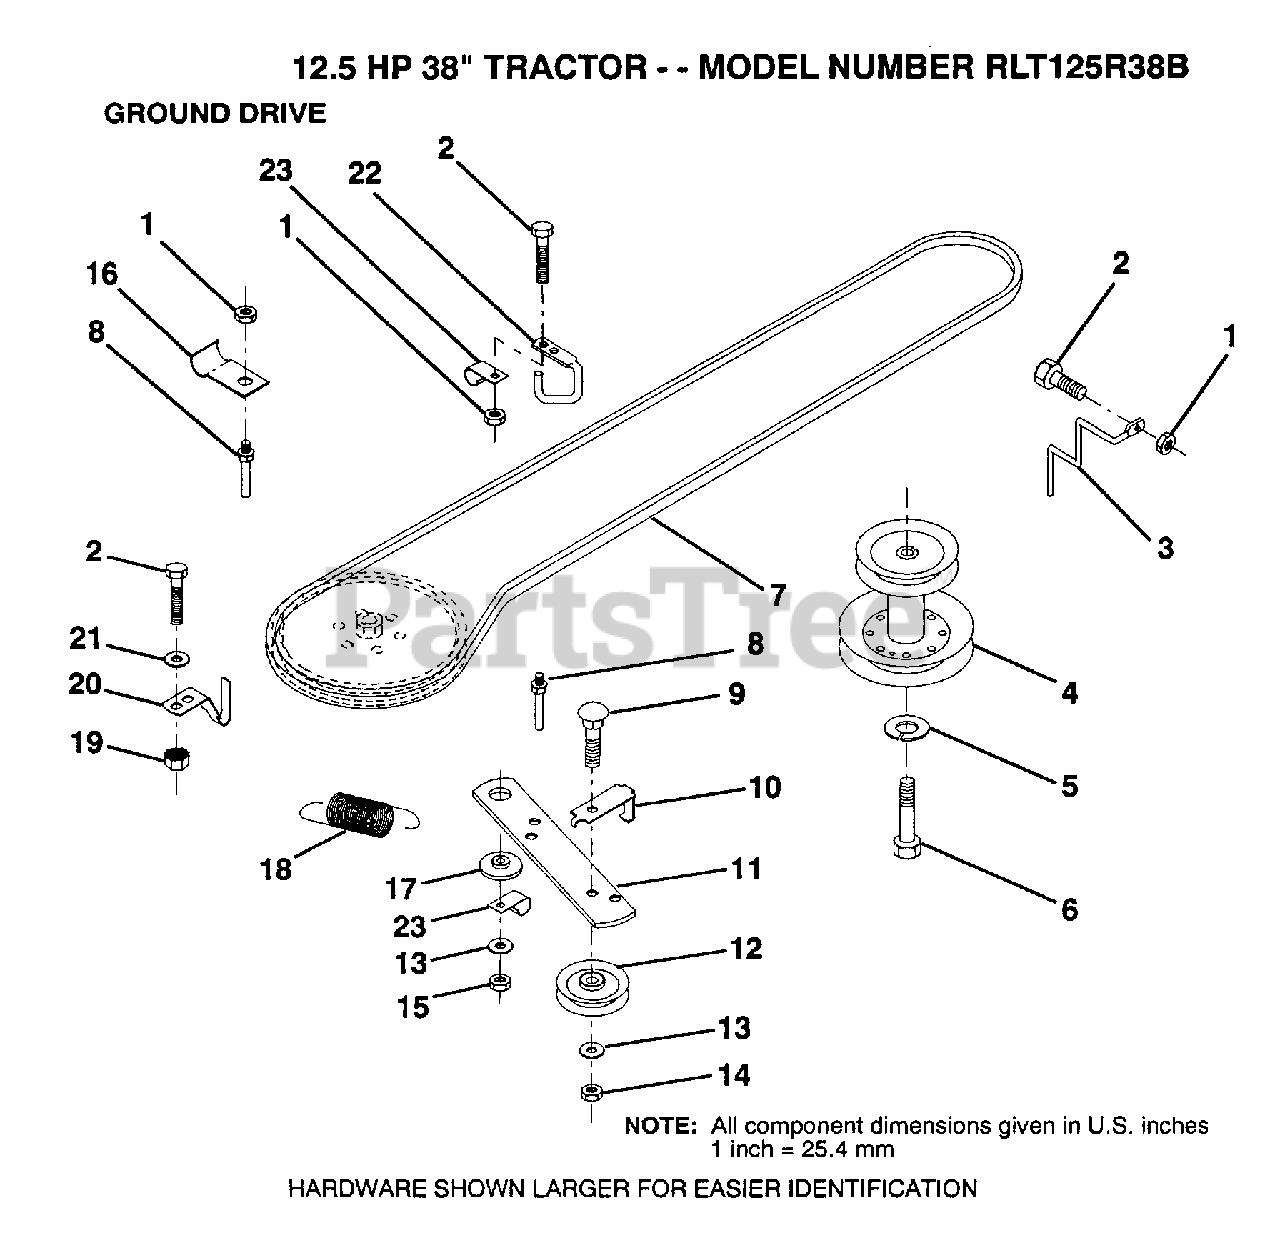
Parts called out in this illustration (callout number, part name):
2	BOLT
3	KEEPER MWR DR BLT
5	LOCKWASHER
6	BOLT
7	BELT
8	"KEEPER,DRIVE BELT"
9	BOLT
10	"KEEP,IDLER DR BEL"
13	WASHER
14	LOCKNUT
16	"CLIP,INSULATOR"
17	SPACER RETAINER
20	"KEEPER,DR BELT "
21	WASHER
22	"KEEPER,FRA DR BEL"
23	CLIP INSULATOR
